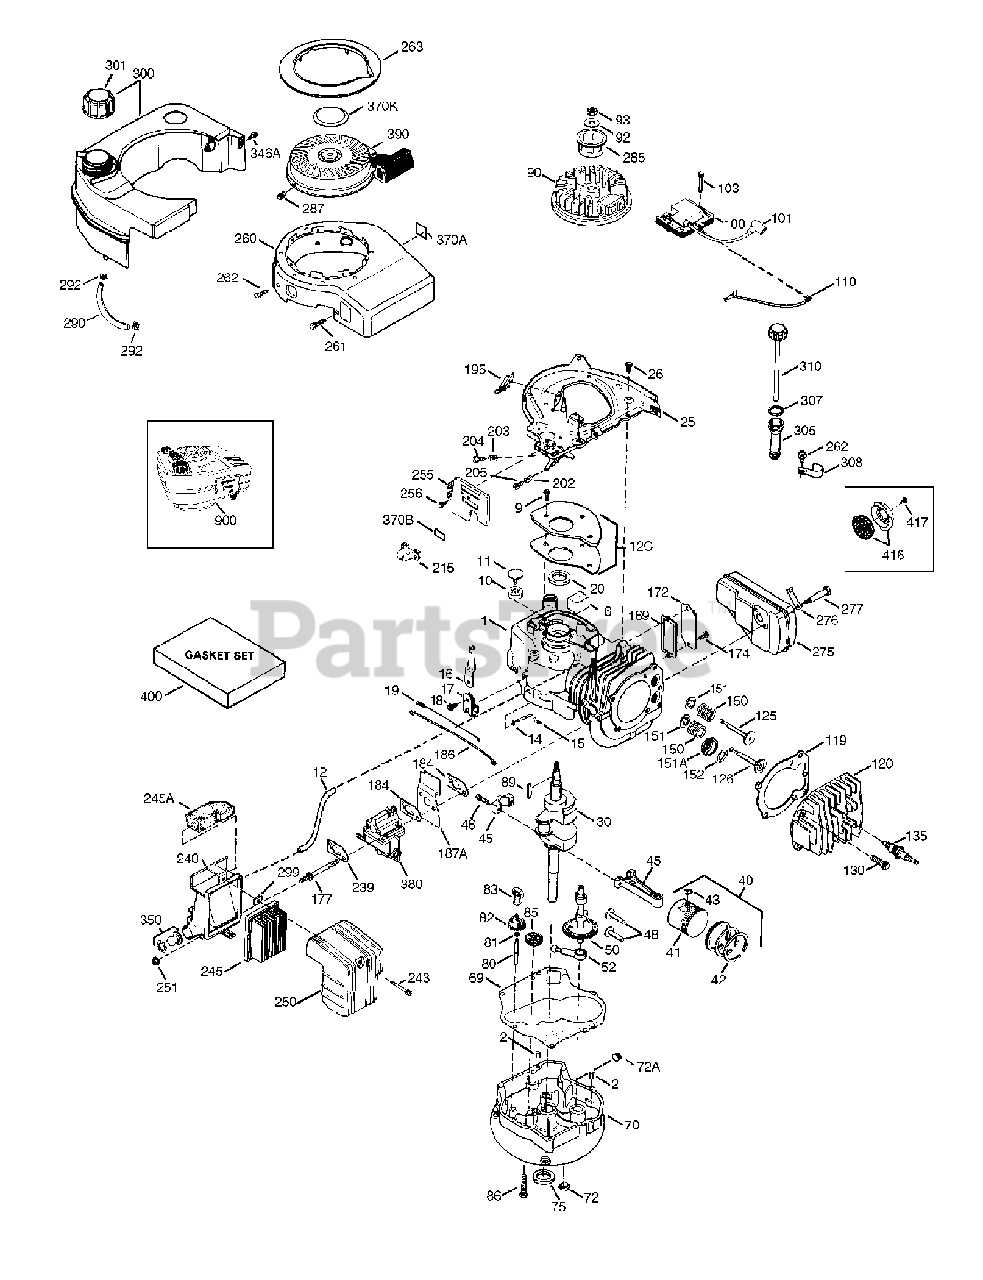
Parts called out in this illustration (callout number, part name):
1	Cylinder
2	Dowel Pin
6	Breather Element
9	Screw 10-24 x .75
10	Breather Valve Body
11	Check Valve
12	Breather Tube
12C	Breather Cover & Gasket
15	Governor Rod
16	Governor Lever
17	Governor Lever Clamp
18	Torx Screw 8-32 x 19/64"
19	Governor Spring
20	Oil Seal
25	Blower Housing Baffle
26	Screw 1/4-20 x 5/8"
30	Crankshaft
40	Piston, Pin, Ring Set (Std)
40	Piston, Pin, Ring Set (.010 OS)
41	Piston & Pin Ass'y (Std)
41	Piston & Pin Ass'y (.010 OS)
42	Ring Set (Std)
42	Ring (.010 OS)
43	Piston Pin Retaining Ring
45	Connecting Rod Ass'y
46	Connecting Rod Bolt
48	Valve Lifter
50	Camshaft
52	Oil Pump Ass'y
69	Mounting Flange Gasket
70	Mounting Flange
72	Oil Drain Plug
72A	Oil Drain Plug
75	Oil Seal
80	Governor Shaft
82	Governor Gear Ass'y
83	Governor Spool
85	Idler Gear
86	Screw 1/4-20 x 1 - 9/16"
89	Flywheel Key
90	Flywheel
92	Bell Washer
93	Flywheel Nut
100	Solid State Ignition
101	Spark Plug Cover
103	Torx Screw 10-24 x 15/16"
110	Ground Wire
119	Cylinder Head Gasket
120	Cylinder Head
125	Exhaust Valve (Std)
125	Exhaust Valve (1/32" OS)
126	Intake Valve (Std)
130	Screw 5/16-18 x 1-1/2"
135	Resistor Spark Plug
150	Valve Spring
151	Lower Valve Spring Cap
151A	Intake Valve Seal
169	Valve Spring Box Gasket
172	Valve Spring Box Cover
174	Screw 10-24 x 9/16"
177	Carburetor Mounting Stud
184	Carburetor Gasket
186	Governor Link
187A	Air Baffle
195	Terminal Ass'y
202	Compression Spring
203	Compression Spring
204	Torx Screw 5-40 x 7/16"
205	Torx Screw 6-32 x 17/32"
215	Control Knob
239	Carburetor to Air Cleaner Gasket
240	Air Clean Body
243	Screw 10-32 x 2 3/32"
245	Air Cleaner Filter
245A	Air Cleaner Filter
250	Air Cleaner Cover
251	Lock Nut 1/4-20
255	Control Plate
256	Screw 8-32 x 17/32"
260	Blower Housing
261	Screw 1/4-20 x 11/16"
262	Screw 1/4-20 x 1/2"
263	Trim Ring
275	Muffler
276	Locking Plate
277	Screw 5/16-18 x 2 11/32"
285	Starter Cup
287	Screw 8-32 x 21/64"
290	Fuel Line
292	Fuel Line Clamp
299	U Type Nut Clip
300	Fuel Tank
301	Fuel Cap
305	Oil Fill Tube
307	"O" Ring
308	Fill Tube Clip
310	Dipstick
346A	Screw 10-32 x 35/64"
370B	Control Decal
370K	Starter Decal
380	Carburetor
390	Rewind Starter
400	Gasket Set
416	Spark Arrestor Kit
417	Screw 10-32 x 1/2"
900	Short Block
